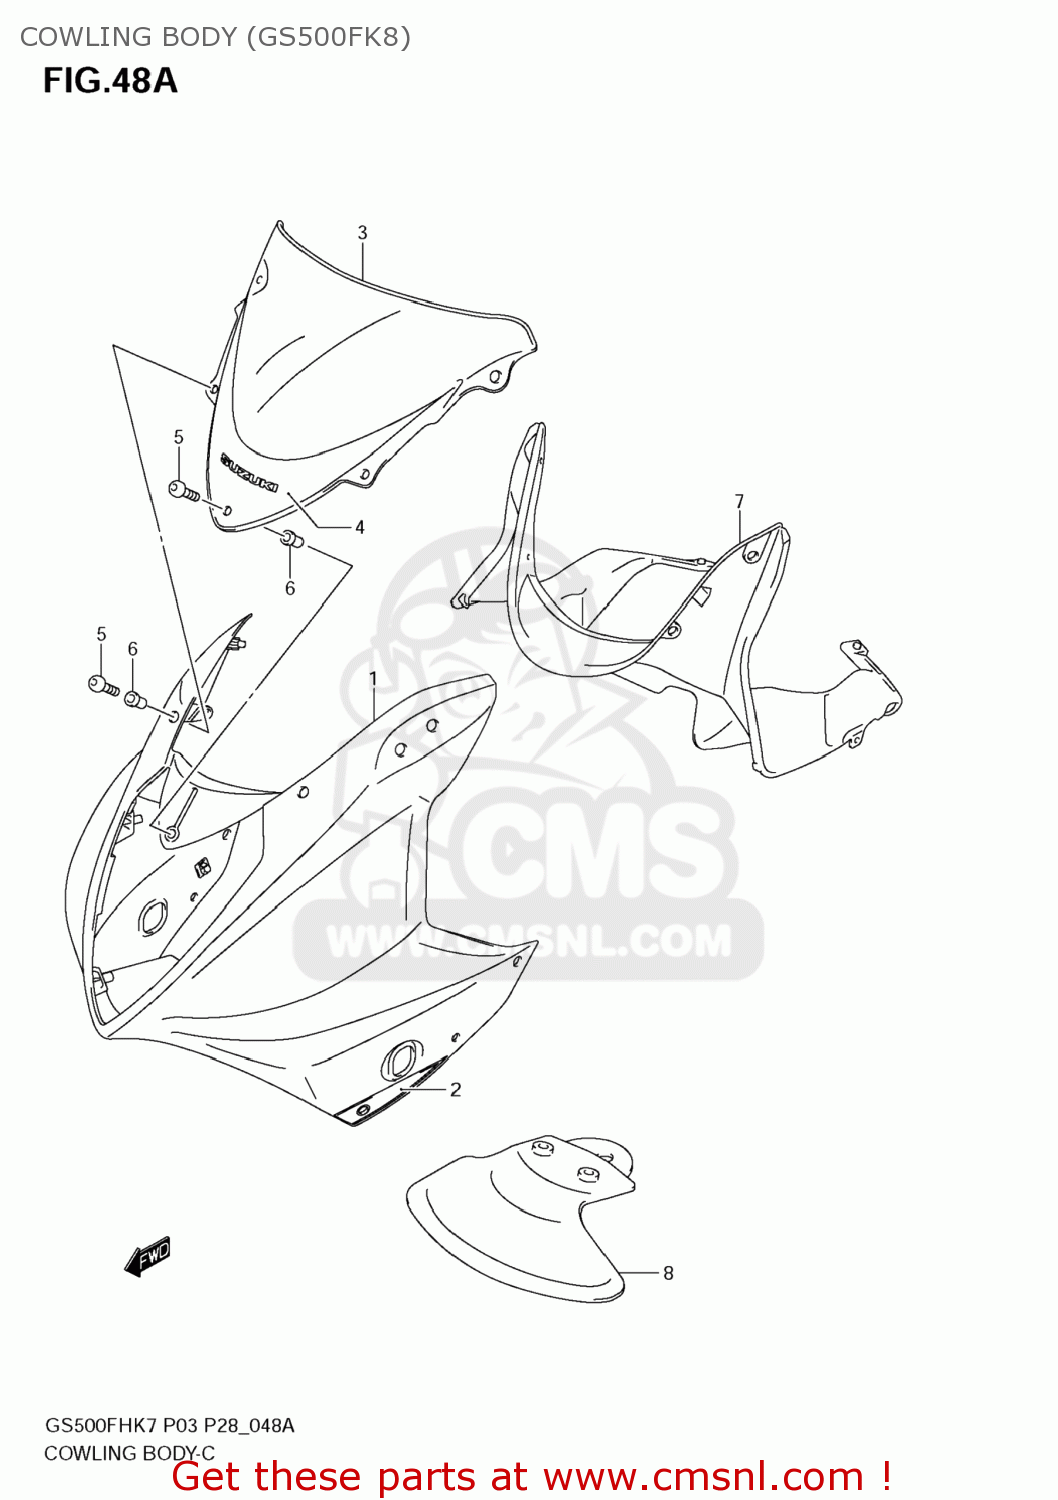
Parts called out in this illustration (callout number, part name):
1	BODY,COWLING G
2	TAPE SET,FRAME
3	WINDSCREEN
4	TAPE,WINDSCREEN
5	SCREW(5X18)
6	NUT
7	PANEL GS500F
8	COVER,LOWER BRA
